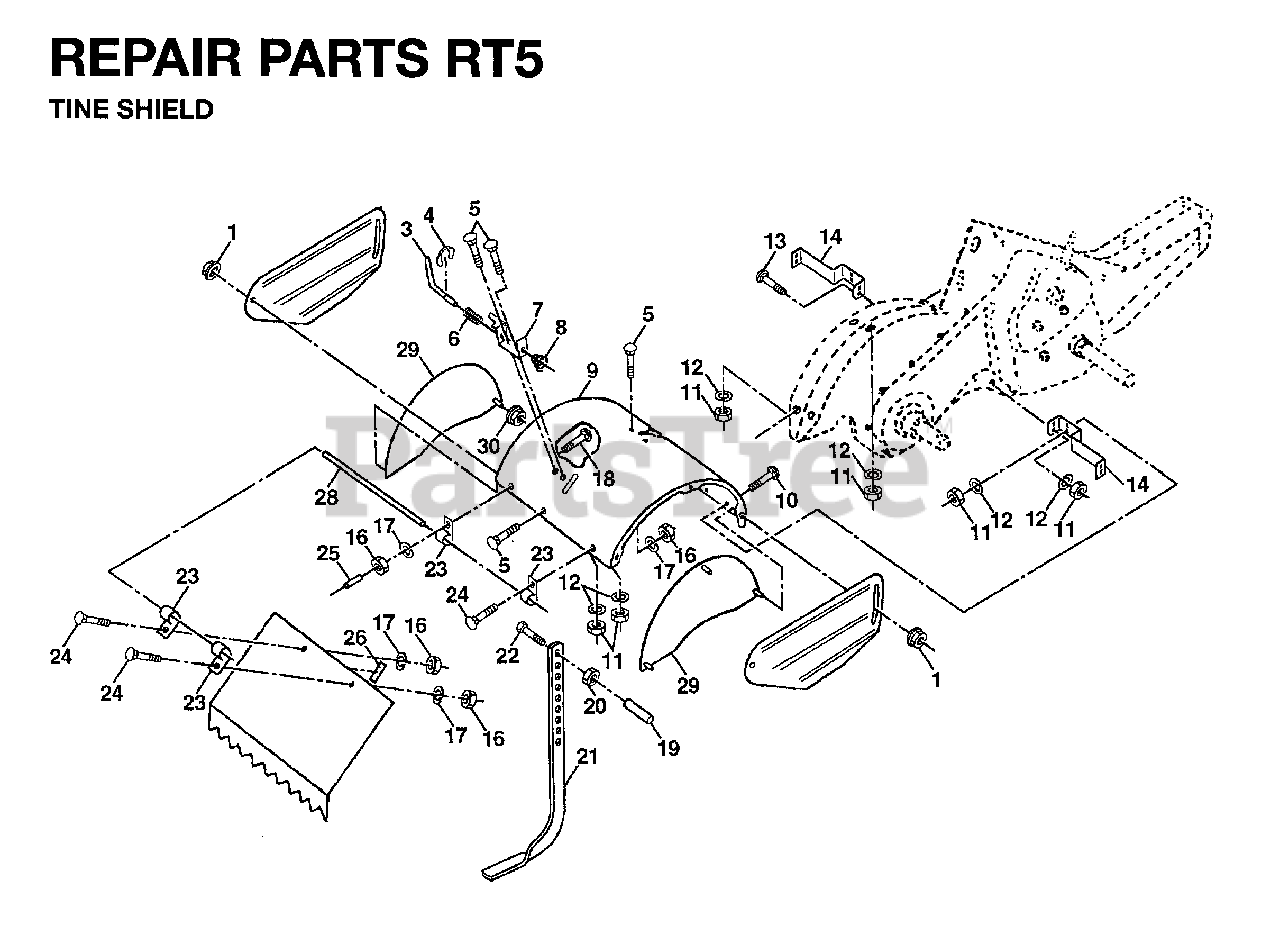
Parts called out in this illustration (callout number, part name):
1	LOCKNUT
3	STAKE PIN TI
4	KLIP RING TI
5	BOLT
6	SPRING TI
7	LATCH BRACKET TI
8	SPRING CRT
10	BOLT
12	LOCKWASHER
13	BOLT.CARRIAGE.5/16-18
14	BRACKET.TINE.SHIELD.TILLER
16	NUT
17	LOCKWASHER
20	NUT.HEX.3/8-16UNC
22	BOLT.375-16
23	HINGE CRT
25	VINYL CAP TI
26	PAD IDLER TI
28	PIN.HINGE.TILLER
30	LOCKNUT
